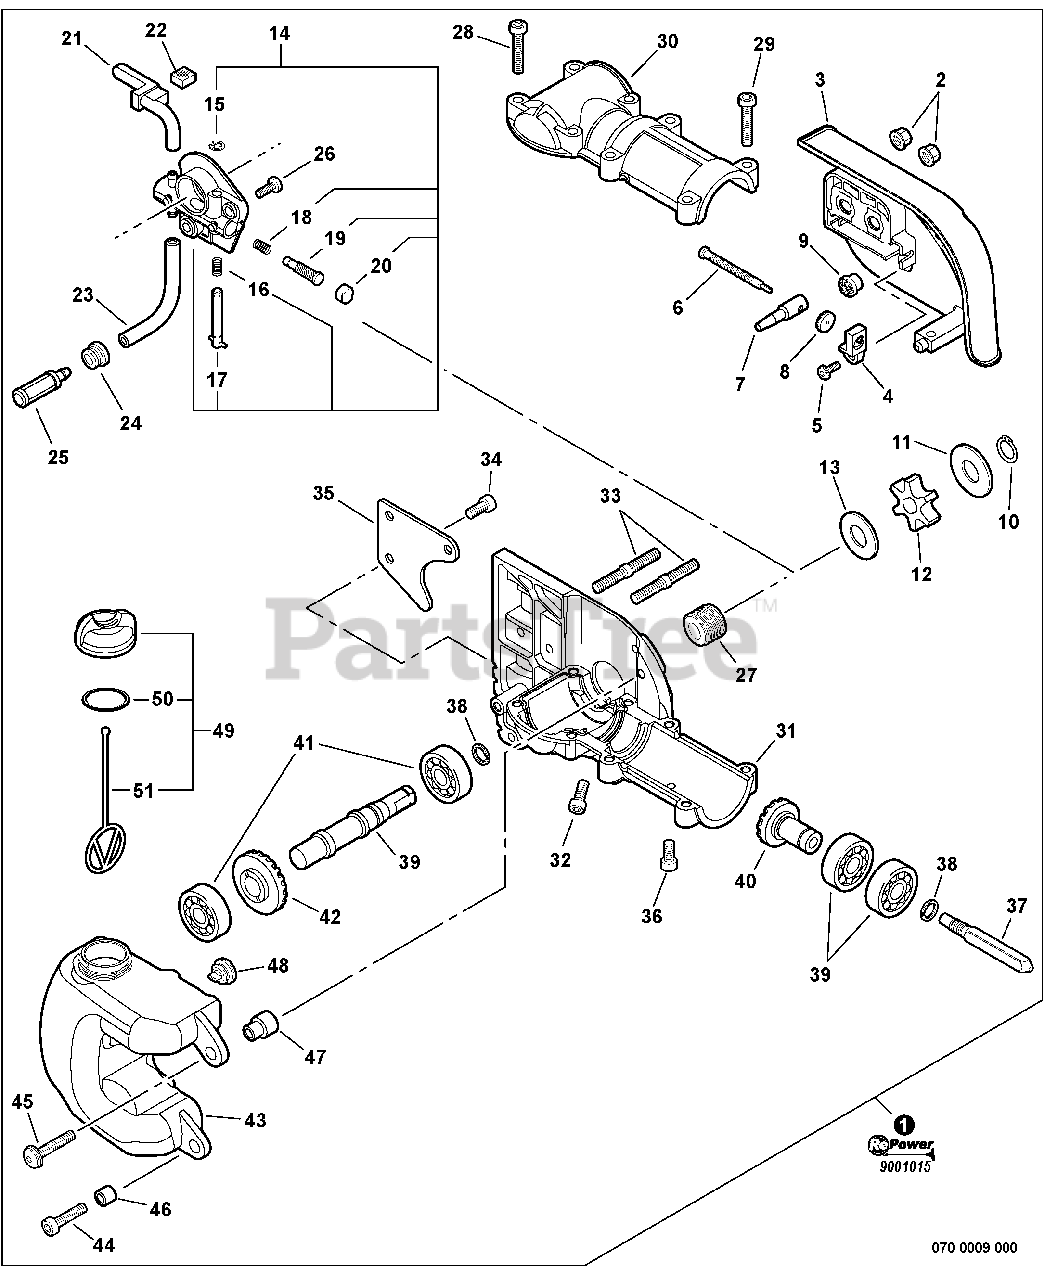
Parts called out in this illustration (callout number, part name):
1	GEAR CASE ASSY
2	NUT, FLANGE M6
3	GUARD, SPROCKET
4	COLLAR 8
5	SCREW 4
7	TENSIONER, CHAIN
8	GEAR - 14 TOOTH
9	GEAR - 14 TOOTH
10	RING, SNAP
11	WASHER 10
12	SPROCKET, DRIVE
13	WASHER 10.2×24.5×1.2
14	AUTO-OILER ASSY
17	ADJUSTER, OILER
19	PLUNGER ASSY
20	CAP, PLUNGER
21	PIPE, OIL OUTLET
22	PAD, FOAM
23	PIPE, IMPULSE 3×6×75
24	GROMMET
25	FILTER, OIL
26	SCREW 5×10
27	GEAR, WORM
28	SCREW M5×25
29	BOLT 5×25
30	CASE, GEAR - UPPER Ø35
31	CASE, GEAR
32	SCREW 5×10
33	BOLT, STUD 6
34	SCREW 5×10
36	BOLT M5×10
37	CONNECTOR, DRIVE SHAFT
38	RING, SNAP Ø12
39	BEARING, BALL
40	GEAR, BEVEL - 15 TOOTH
41	SHAFT, GEAR
42	GEAR, BEVEL - 23 TOOTH
43	TANK, OIL
44	BOLT 5×20
45	SCREW M5×25
46	SPACER 6.2×7.8×6
47	COLLAR 6
48	VENT ASSY
49	CAP ASSY
50	O-RING 18
51	CONNECTOR, CAP L= 60 MM
